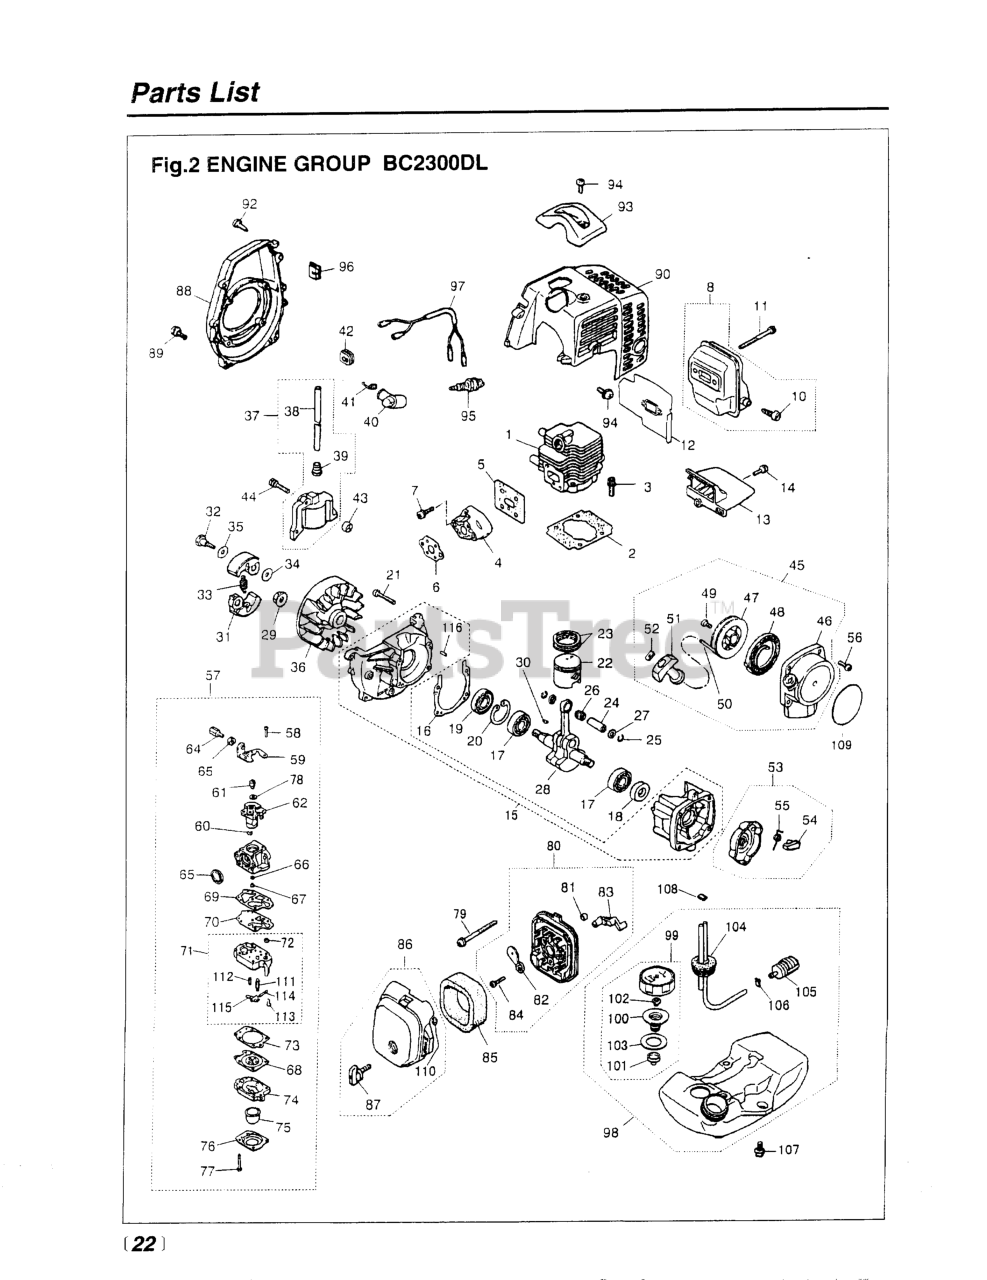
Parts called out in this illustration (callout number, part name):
1	CYLINDER
3	BOLT, M5 X 22
7	SCREW, M5X20 (RPLS.1400-75510)
8	MUFFLER ASSY (RPLS 5501- )
10	ARRESTER (RPLS 5850-15140)
11	BOLT, M5 x 50
14	SCREW, M4 X 16
15	CRANKCASE
17	BEARING
18	SEAL, OIL (RPLS 1100-21210)
19	SEAL, OIL (RPLS 1140-21220)
20	RING, SNAP, M28 x 1.2
21	BOLT, M5 X 30
22	PISTON (REPLACES 1140-41110)
23	RING, PISTON (RPLS 1850-41210)
24	PIN, PISTON 5x8x26
25	RING, SNAP (RPLS 1101-41320)
27	WASHER
28	CRANKSHAFT (RPLS 1850-42000)
30	KEY
32	BOLT
33	SPRING, CLUTCH (RPLS-51220)
34	WASHER, FLAT (USE 182303)
36	ROTOR
37	COIL ASSY (RPLS 5500-71200)
38	CORD
39	CAP
41	SPRING
42	GROMMET
43	SPACER (RPLS -71260)
44	BOLT
45	RECOIL ASSEMBLY
46	CASE
47	REEL
48	SPRING, SPIRAL
49	SCREW (RPLS -75150)
51	KNOB
52	PLATE, STOPPER
53	PULLEY ASSY (RPLS -75210)
54	RATCHET (RPLS 1850-75220)
55	SPRING, RETURN
56	SCREW, M4 X 16
57	CARBURETOR
58	SCREW
60	RING
61	SWIVEL
62	VALVE ASSY
63	SCREW, CABLE ADJUSTER
64	NUT, CABLE ADJUSTER
65	RING, PACKING
66	RING, O
67	JET
68	DIAPHRAGM (USE 4810-81260)
69	GASKET, PUMP
70	DIAPHRAGM
71	BODY, PUMP
73	GASKET, DIAPHRAGM
74	BODY, PURGE
75	PUMP, PRIMING
76	COVER, PUMP
77	SCREW
78	WASHER
79	SCREW, M5 x 60
80	BODY-A (RPLS -82101)
81	SLEEVE
82	PLATE, CHOKE (RPLS-82130)
83	LEVER, CHOKE
84	SCREW (REPLACES 50030272)
85	ELEMENT
87	KNOB (RPLS -82220)
88	COVER, FAN (RPLS-31110)
89	SCREW, M5X20 (RPLS.1400-75510)
91	SCREW, M5 x 12
92	SCREW, HOUSING
93	GUARD, PLUG
94	SCREW,M5 X 14 (RPLS 1400-15510
97	CORD COMP (RPLS -73200)
101	HOLDER, CAP
102	VALVE (NLA WHEN OUT)
103	PACKING
104	PIPE COMPLETE
105	FILTER (RPLS 1850-85300)
106	CLIP (REPLACES 2841-31280)
107	SCREW
108	CLIP
109	LABEL, RECOIL (RPLS -91121)
110	RING
111	VALVE, INLET
112	SPRING, METERING LEVER
113	SCREW, METERING LEVER PIN
114	PIN, METERING LEVER
115	LEVER
116	PIN
